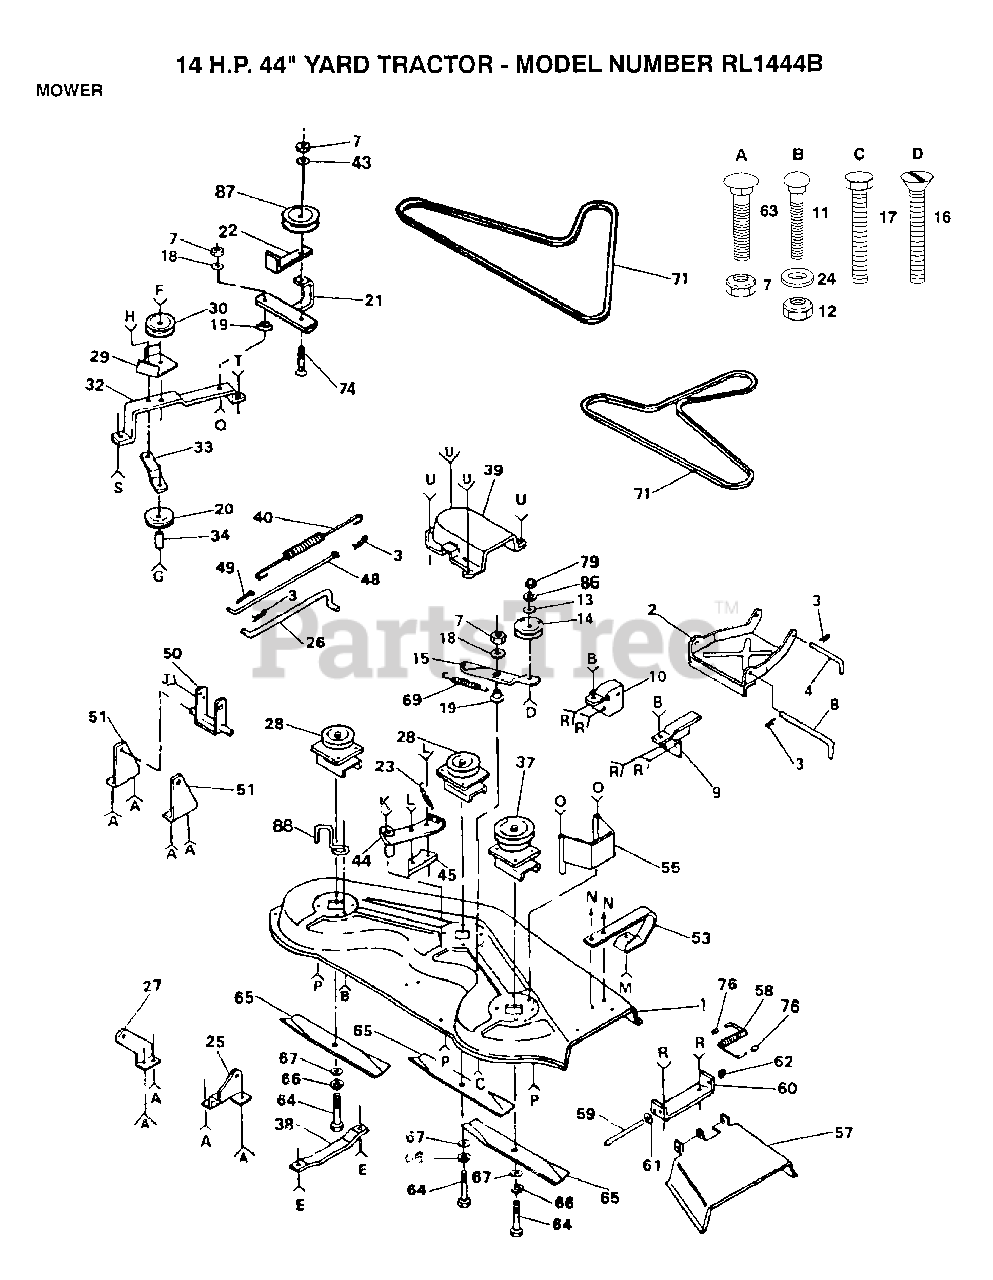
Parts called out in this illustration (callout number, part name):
2	"STOP, LINK PARAL"
3	SPRING.RETAINER
4	"ROD, FRT. PARAL T"
8	HINGE PIN T
9	BRACKET RH YT
10	BRACKET LH YT
11	BOLT
13	WASHER
14	IDLER.FLAT.GTV
15	ARM-IDLER YT
16	SCREW YT
18	"WASHER, WEAR LT"
18	SPACER RETAINER
19	SPACER RETAINER
20	IDLER-FLAT T
22	GUIDE BELT
23	SPRING-EXT YT
24	WASHER M
25	BRKT SUSP REAR RH
27	BRKT SUSP REAR LH
29	GUIDE-BELT YT
30	IDLER-INSIDE T
32	"SUPPORT YT, BAR"
33	BRACE-IDLER YT
34	SPACER
38	RUNNER-LH M
39	GUARD YT
43	WASHER
44	BRAKE ARM LT
45	BRAKE-BLOCK YTV
48	ROD BRAKE YT
51	SUPPORT SHAFT YT
55	ASSY RH BELT GRD
57	DEFLECTOR SHIELD
59	ROD-HINGE T
61	WASHER
62	NUT PUSH M
63	BOLT
64	BOLT.3/8-24X1-1/2
67	WASHER
71	BELT-V.79.1.MWR
74	BOLT
76	CAP-SLEEVE LT
79	NUT.HEX.3/8-16UNC
86	LOCKWASHER
87	PULLEY IDLER
88	BELT RETIANER
